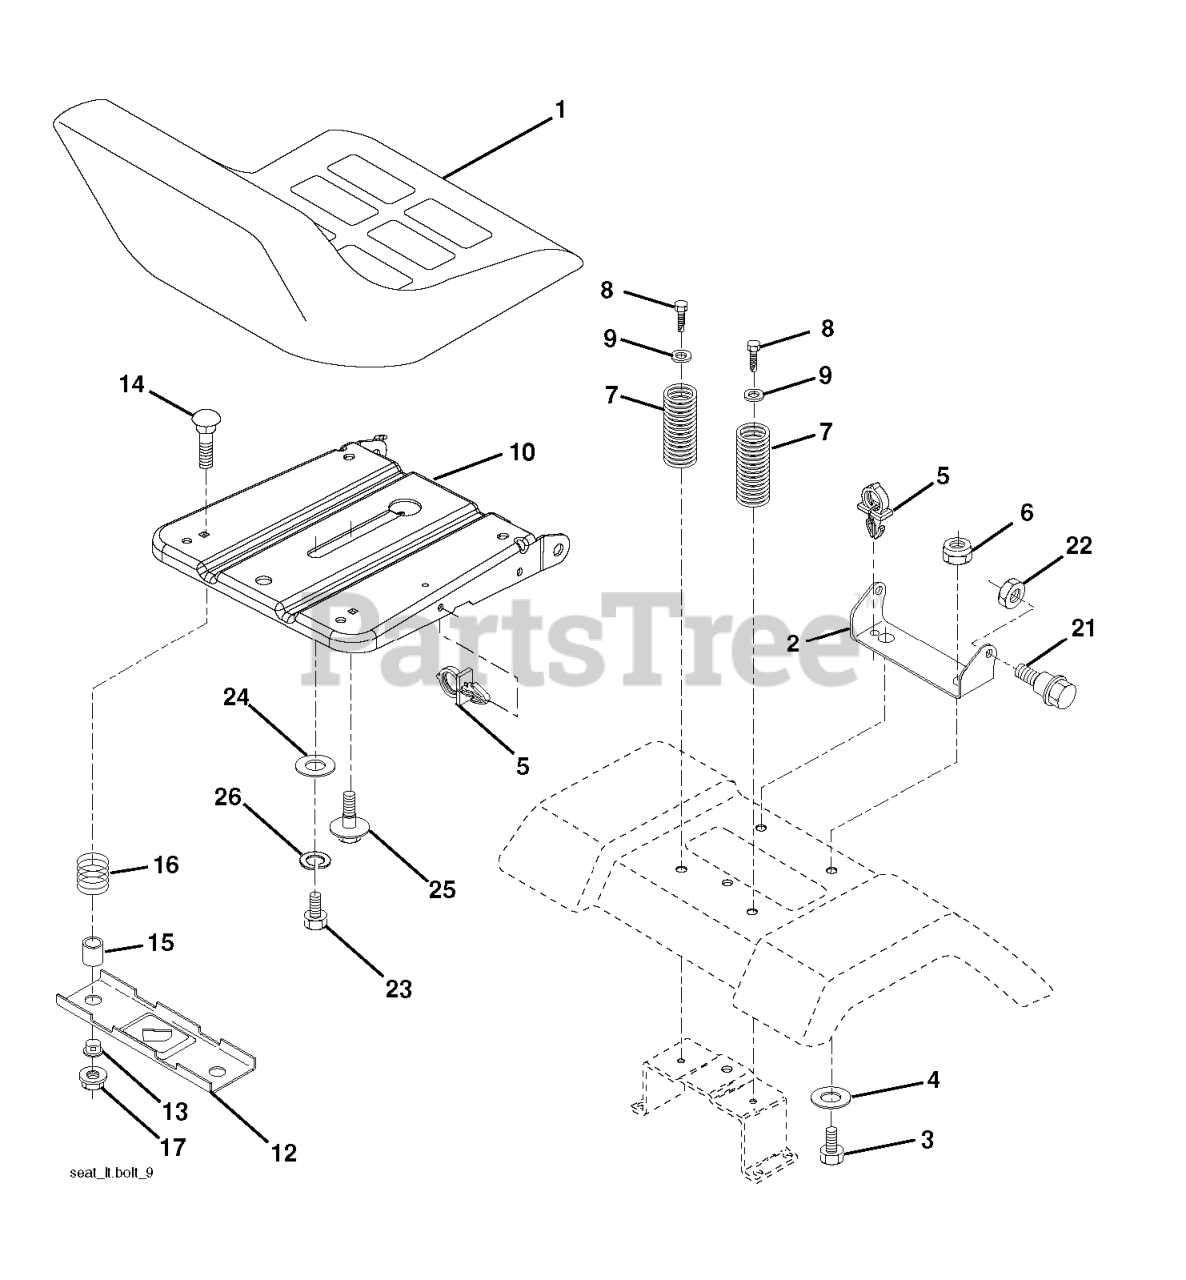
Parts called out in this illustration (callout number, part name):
1	SEAT.XG090.BLK.KB/BLT.NO-LOG
2	SEAT PIVOT BRKT
3	BOLT, HEX 3/8-16X1
6	NUT
7	SPRING COMPRESSION
8	SCREW 3/8-16X1
9	WASHER
10	PAN.ASM.SEAT.1SLOT
12	BRKT.MNTNG.SWITCH.SEAT.BLACK
14	BOLT.ROUND.HEAD.SQUARE.NECK
15	SPACER SPLIT 28X.96
17	NUT T
21	BOLT.SHOULDER.5/16-18
22	NUT.71038.31-18.HEX.NYLOCK
23	BOLT.HEX.BLACK
25	BOLT,SHOULD
26	LOCKWASHER
